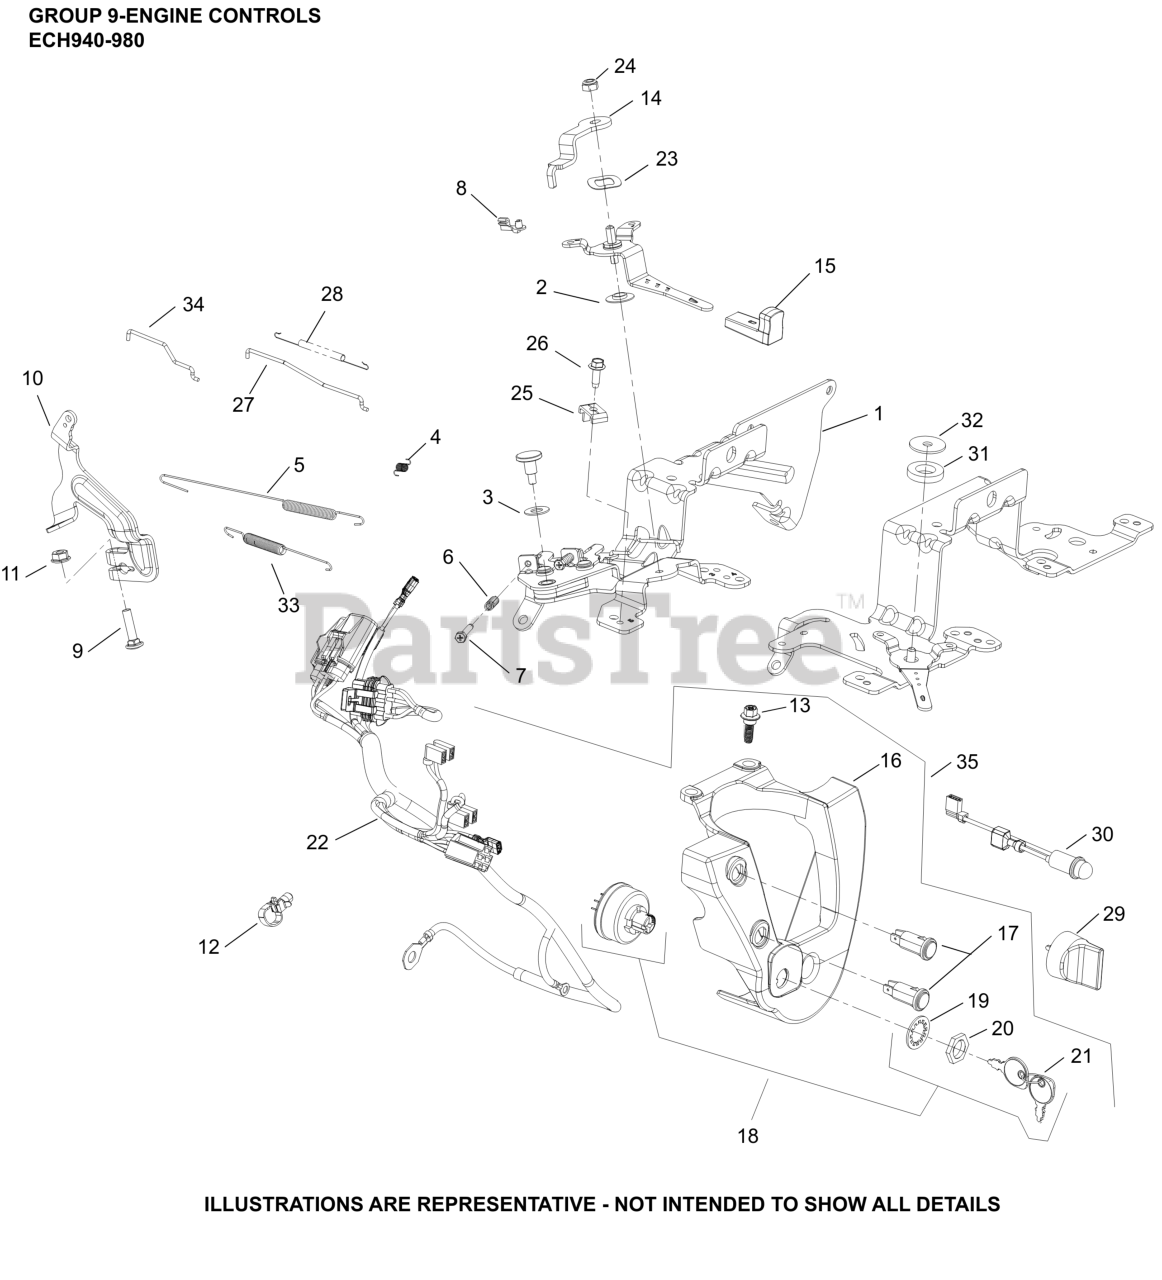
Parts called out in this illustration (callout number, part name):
1	CONTROL ASSEMBLY, SPEED (H/S EFI)
2	WASHER, NYLON SHOULDER
3	WASHER, FLAT 9 MM
4	SPRING, RETURN
5	SPRING, GOVERNOR, HIGH SPEED
6	SPRING, SPEED CONTROL (SHORT)
7	SCREW, PHL THD FRM M4X0.7X25
8	BUSHING, THROTTLE LINKAGE
9	BOLT, RD HD SQ NECK M6X1.0X25
10	KIT, GOVERNOR LEVER
11	NUT, FLG M6X1.0
12	TIE, WIRE
25	CLAMP, CABLE CABLE
26	SCREW, THREAD FORMING
27	LINKAGE, THROTTLE
28	SPRING, LINKAGE
33	SPRING, GOV (HORZ IDLE 1626-1800)
34	LINKAGE, CONTROL LEVER
